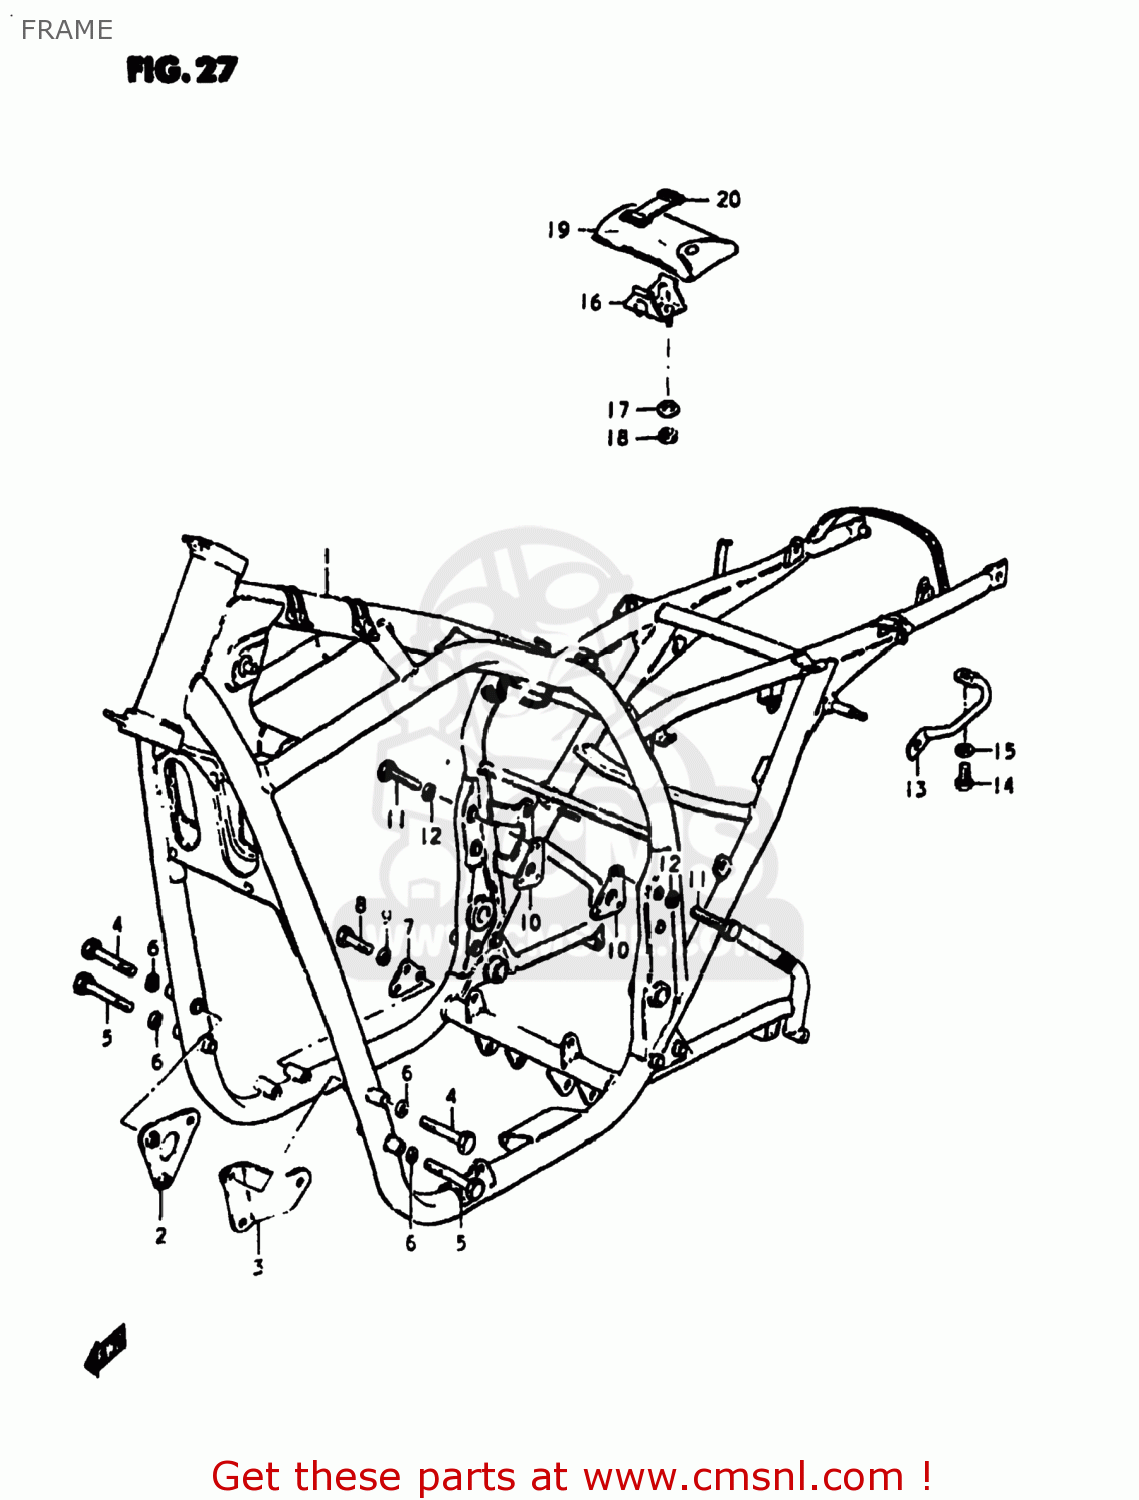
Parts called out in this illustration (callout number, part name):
1	FRAME
2	PLATE,ENGINE MOUNTING
3	PLATE,ENGINE MOUNTING
4	BOLT
5	BOLT
6	LOCK WASHER
7	PLATE,ENGINE MOUNTING
8	BOLT
9	LOCK WASHER
10	PLATE,ENGINE MOUNTING
11	BOLT
12	LOCK WASHER
13	GRIP,FRAME
14	BOLT
15	WASHER
16	HOLDER,TOOL
17	WASHER
18	NUT
19	TOOL SET
20	BAND
